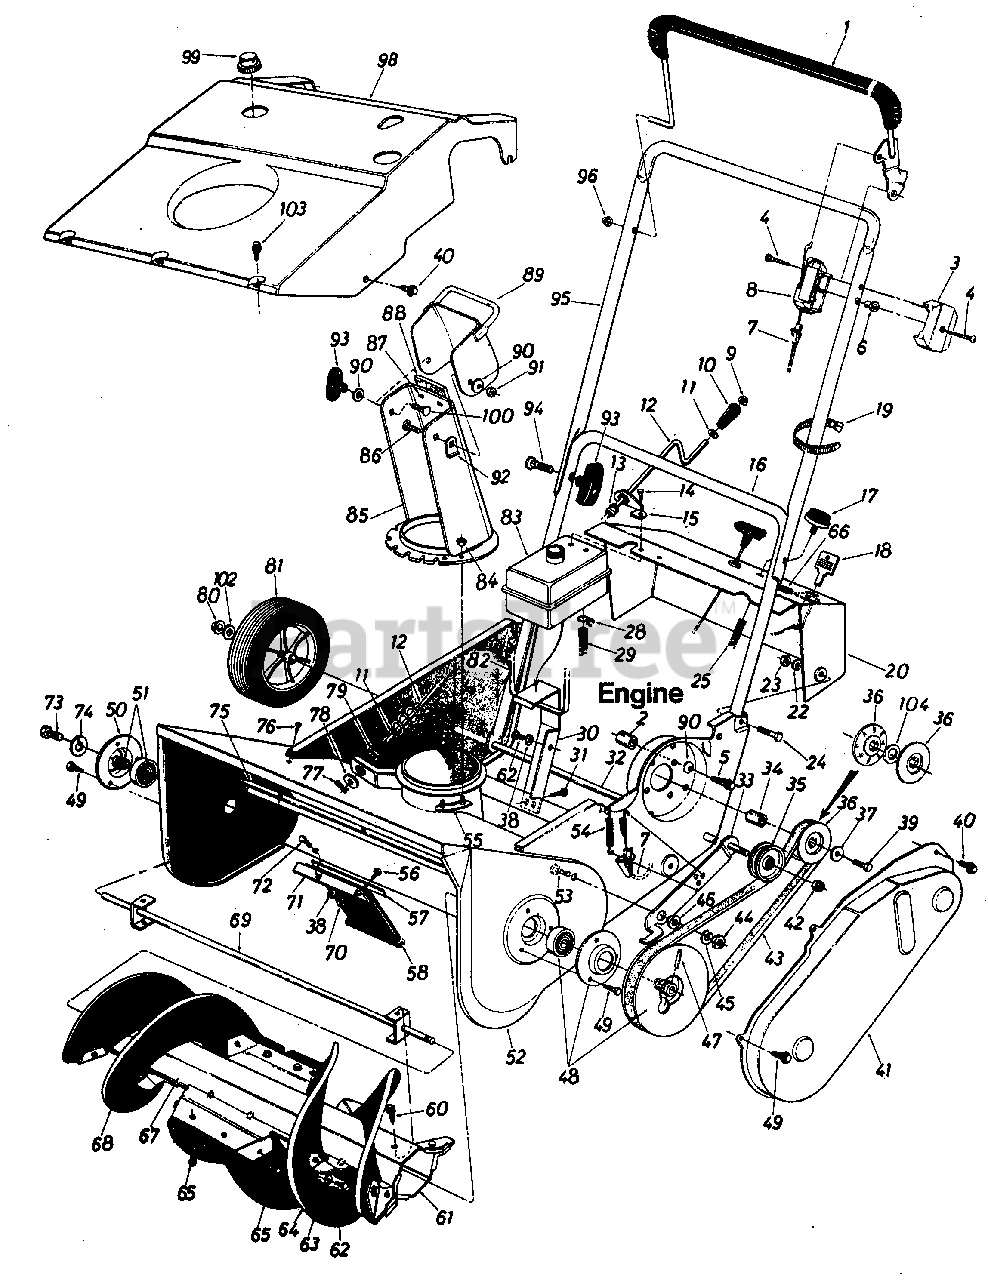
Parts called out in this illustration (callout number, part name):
1	Clutch Control Handle Ass'y.
2	Spacer.325" I.D. x .625" O.D. x.87" Lg.
3	Control Panel Half
4	Truss Mach. Hi-B Tap Scr. #12 x 1.50" Lg.
5	Hex Bolt 5/16-18 x 1.50" Lg.*
6	Control Disc Pin
7	Clutch Cable 35" Lg. Black
8	Clutch Panel Half
9	Push Nut 3/8" Rod
10	Knob Black 3/8" Dia. Hole
11	Fl-Wash. .385" I.D x .62" O.D.
12	Chute Crank Ass'y.
13	Chute Crank Grommet
14	Hex Tap Scr. 1/4" x .75" Lg.
15	Upper Chute Crank Brkt.
16	Lower Handle
17	Primer
18	Starter Key
20	Dash Panel Ass'y.
22	L-Wash. 5/16" I.D.*
23	Hex Nut 5/16-18 Thd.*
24	Hex Bolt 5/16-18 x 1.50" Lg.
25	Primer Hose 118" I.D. x 11"
28	Hose Clamp .406" Dia.
29	Gas Line 9" Lg.
33	Idler Brake Brkt. Ass'y.
35	Fl-ldler 2.00" x 1" w/ Flange
36	3/8" V-Pulley .625" I.D. x 2.25
37	Bell-Wash. .345" I.D. x .88"
38	L-Wash. 1/4" I.D.*
39	Hex Scr. 5/16-24 x .75" Lg.*
40	Hex L-Wash. Hd. AB-Tap Scr. 1/4 x.62"
42	Hex L-Nut 3/8-24 Thd.
43	V-Belt 1/2" x 34" Lg.
44	Hex Nut 5/16-18 Thd.*
45	L-Wash. 5/16" I.D.*
46	Shld. Spacer 1.0" O.D. x .315 I.D.
47	Spring Pin Spir. 1/4" Dia. x 1.00" Lg.
48	Kit-Bearing, Cup and Pulley
49	Hex "B"-Tap Scr. 1/4-20 x .38" Lg.
52	Blower Housing Ass'y.
53	Truss. Mach. Scr. 5/16-18 x 751' La.
54	Extension Spring .33" O.D. x 1.12" Lg.
55	Chute Flange Keeper Ass'y.
56	Hex Wash. AB-Tap Scr. 114" x.62" Lg.
57	Retaining Strip 19.0" Lg.
58	Rear Flap 4.69" x 18.2"
60	Hex L-Wash. Hd. AB-Tap Scr. 1/4 x .62" Lg.
61	Auger Half 21.0" Lg.
62	Hex Wash. Hd. Self-Tap Scr. 1/4-20 x .50" Lg.
63	Fl-Wash. .28" I.D. x .74" O.D.
64	8.5" Dia. Rubber Spiral
65	Hex B-Tap Scr. 1/4 x .62" Lg.
66	Plastic Plug
67	Auger Half 21.0" Lg.
68	8.5" Dia. Rubber Spiral
69	Auger Axle Ass'y.
70	Hex Nut 1/4-20 Thd.*
71	Shave Plate
72	Carriage Bolt 1/4-20 x .50" Lg.*
73	Hex Wash. TT-Tap Scr. 1/4-20 x .75" Lg.
74	L-Wash. 1/4" I.D.*
75	Thrower Housing Angle
76	Hex "B"-Tap Scr. 1/4" x .38" Lg.
77	Cotter Pin 3/32" Dia. x .75" Lg.
78	Fl-Wash. .385" I.D. x 1.5" O.D.
79	Hex Bushing .385" I.D.
80	Cap Speed Nut 1/2" Rod
81	Wheel Ass'y. 6 x 1.50
82	Cable Tie x 17.75" Lg.
83	Gas Tank
84	Hex Nylon L-Nut 1/4-20 Thd.
85	5.0" Dia. Chute Ass'y.
86	Carriage Bolt 5/16-18 x .62"*
87	Rivet.250" x.44" Lg.
88	Chute Seal
89	Top Chute Ass'y.
90	Bell-Wash. .345" I.D. x .88"
91	Hex Cent. L-N ut 5/16-18 Thd.
92	Top Chute Stop
93	Knob-Handle Ass'y.
94	Curved Hd. Carriage Bolt 5/16-18 x 1.75" Lg.
95	Upper Handle
96	Cap Speed Nut 5/16" Rod
99	Gas Tank Cap
100	Carriage Bolt 5/16-18 x 1.00"*
102	Fl-Wash. .75" O.D. x .50" I.D.
103	Hex AB-Tap Scr. #10 x .50"
104	Fl-Wash. .635" I.D. x .93" O.D.
